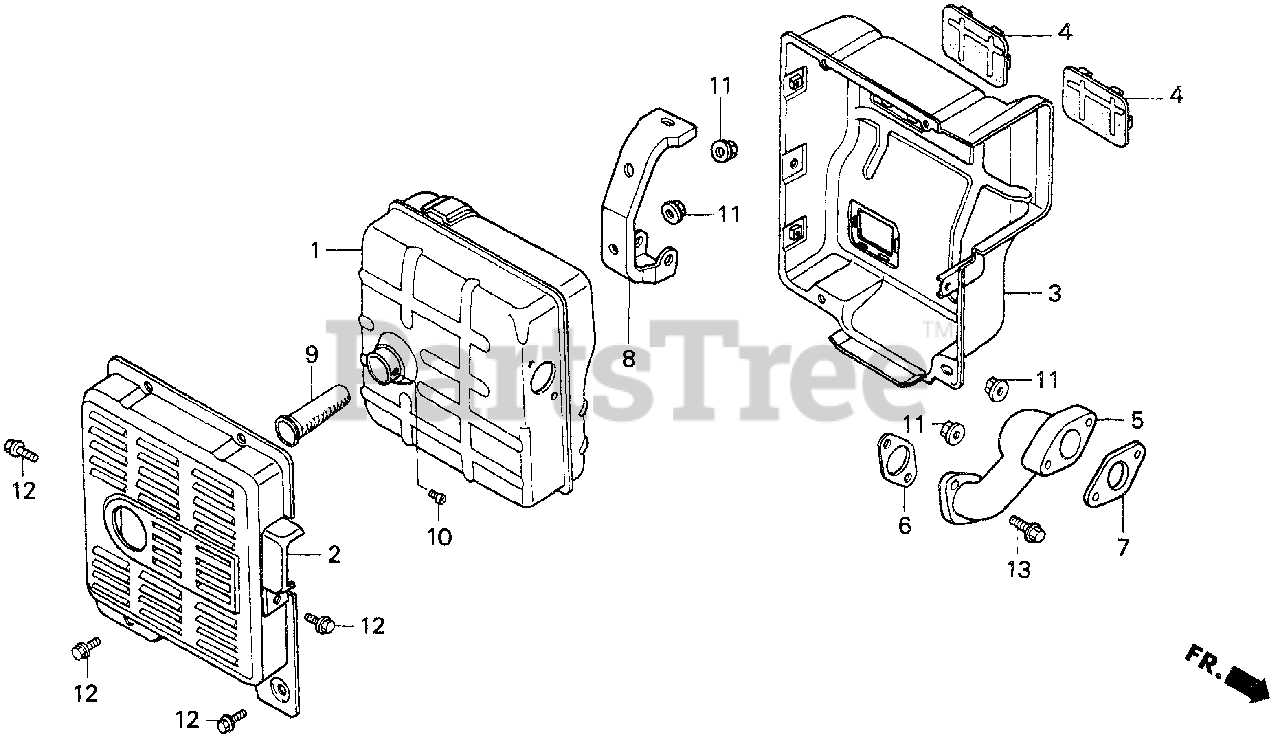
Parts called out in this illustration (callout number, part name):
1	MUFFLER (TSURUMI)
2	PROTECTOR, MUFFLER (OUTER)
3	PROTECTOR, MUFFLER (INNER)
4	SEAL, MUFFLER PROTECTOR
5	PIPE, EX.
6	GASKET, EX. PIPE
7	GASKET, EX. PIPE
7	GASKET, EX. PIPE (WACKER)
8	STAY A, MUFFLER (TSURUMI)
9	ARRESTER, SPARK
10	SCREW, TAPPING (4X8)
11	NUT, FLANGE (8MM)
12	BOLT, FLANGE (6X12)
13	BOLT, FLANGE (8X20)
